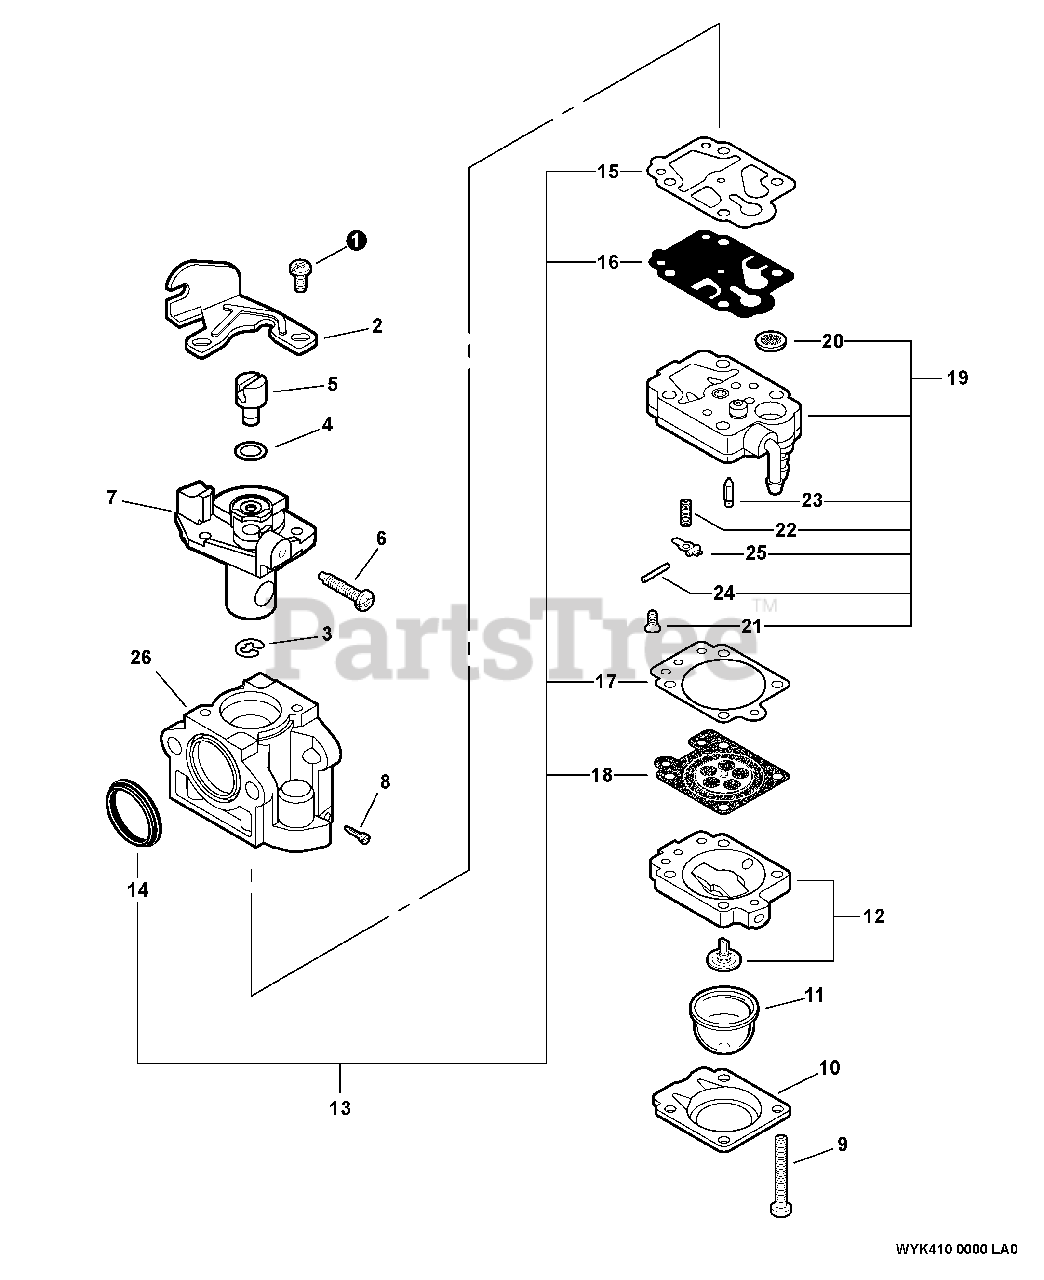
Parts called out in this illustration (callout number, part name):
2	BRACKET, CABLE
3	RING, RETAINING
6	SCREW, IDLE ADJUST
7	THROTTLE VALVE ASSY
8	NEEDLE - HIGH SPEED
9	SCREW, PUMP COVER
10	RETAINER, PURGE BULB
11	BULB, PURGE
12	PURGE BASE ASSY
13	DIAPHRAGM/GASKET KIT
14	SEAL
15	GASKET, PUMP
16	DIAPHRAGM, PUMP
17	GASKET, METERING
18	DIAPHRAGM, METERING
19	PUMP BODY ASSY
20	STRAINER
21	SCREW, METERING LEVER PIN
22	SPRING, METERING LEVER
23	VALVE, INLET NEEDLE
24	PIN, METERING LEVER
25	LEVER, METERING
26	BODY, CARBURETOR
